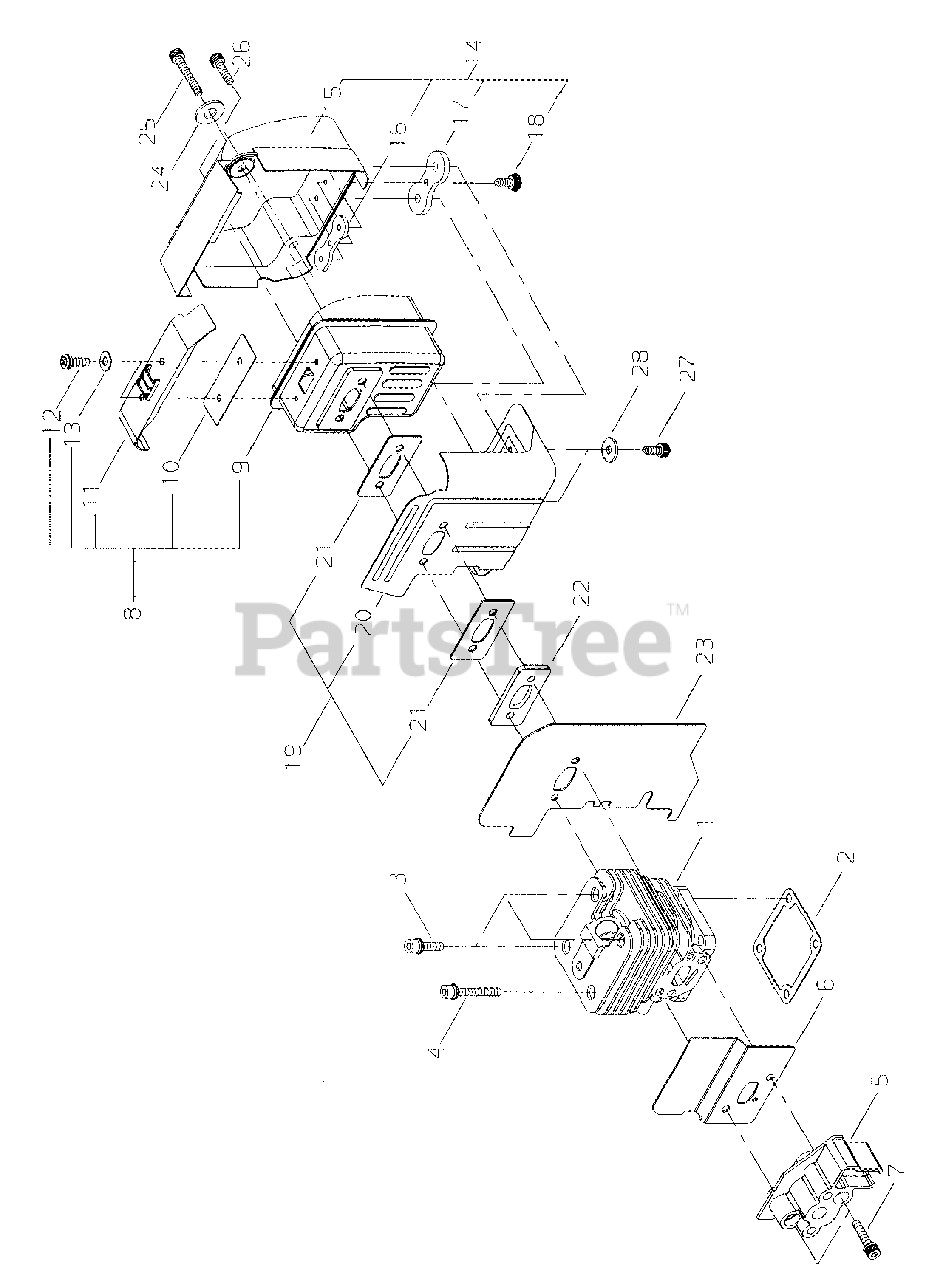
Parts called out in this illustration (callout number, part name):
1	CYLINDER
2	GASKET, CYLINDER
3	SCREW - 5X16
4	SCREW - 5X35
5	INSULATOR, INTAKE
6	SHIELD, INTAKE
7	SCREW - 5X30
8	MUFFLER ASSY
9	MUFFLER
10	SCREEN, SPARK ARRESTOR
11	GUIDE, EXHAUST
12	SCREW - 4X6
13	WASHER - 4
14	EXHAUST COVER ASSY
15	COVER, EXHAUST
16	PLATE
17	SPACER
18	SCREW - 4X8
19	EXHAUST SHIELD KIT
20	SHIELD, EXHAUST
21	GASKET, EXHAUST
22	SPACER
23	GASKET, EXHAUST
24	WASHER - 5
25	SCREW - 5X65
26	SCREW - 5X25
27	SCREW - 5X10
28	COLLAR - 15X5.2X1.6
